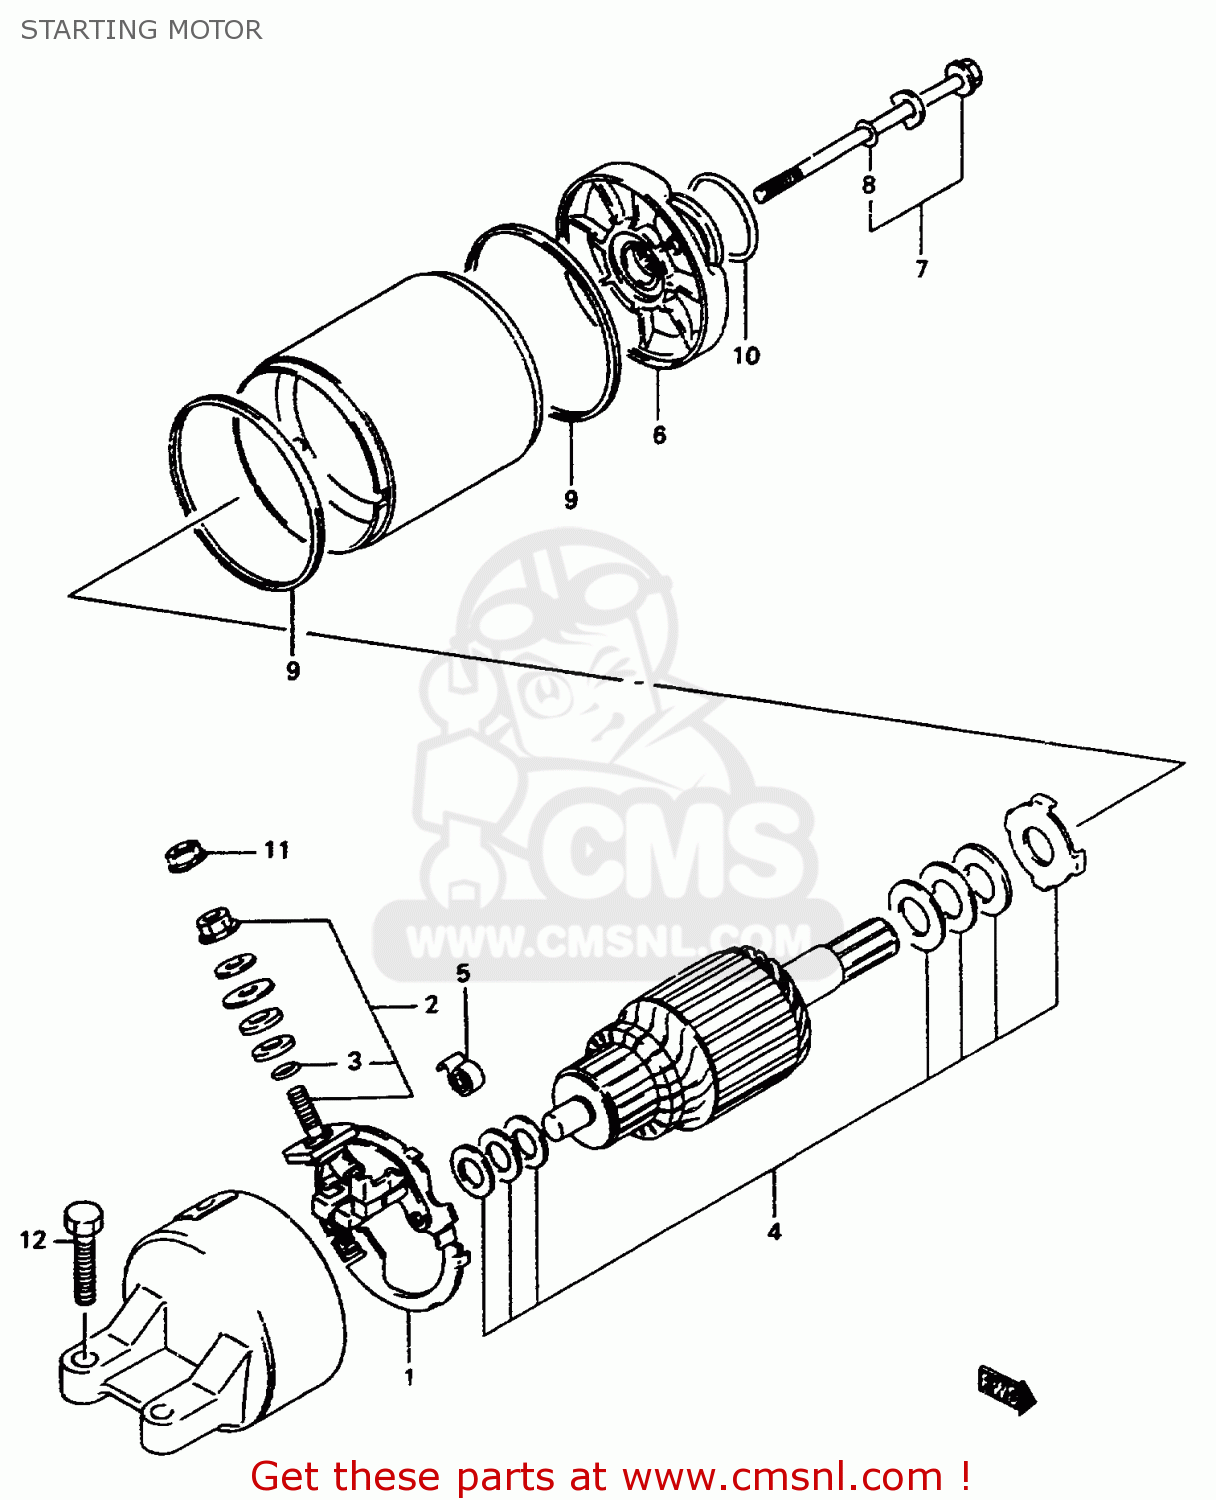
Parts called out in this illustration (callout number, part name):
1	HOLDER SET,BRUSH
2	TERMINAL SET,BRUSH,PLUS
3	O RING
4	SHIM SET,STARTING MOTOR
5	SPRING,BRUSH
6	BRACKET ASSY,FR
7	BOLT SET,STARTING MOTOR
8	O RING
9	O RING
10	O RING(D:3,ID:24.5)
11	NUT
12	SCREW (6X25)
